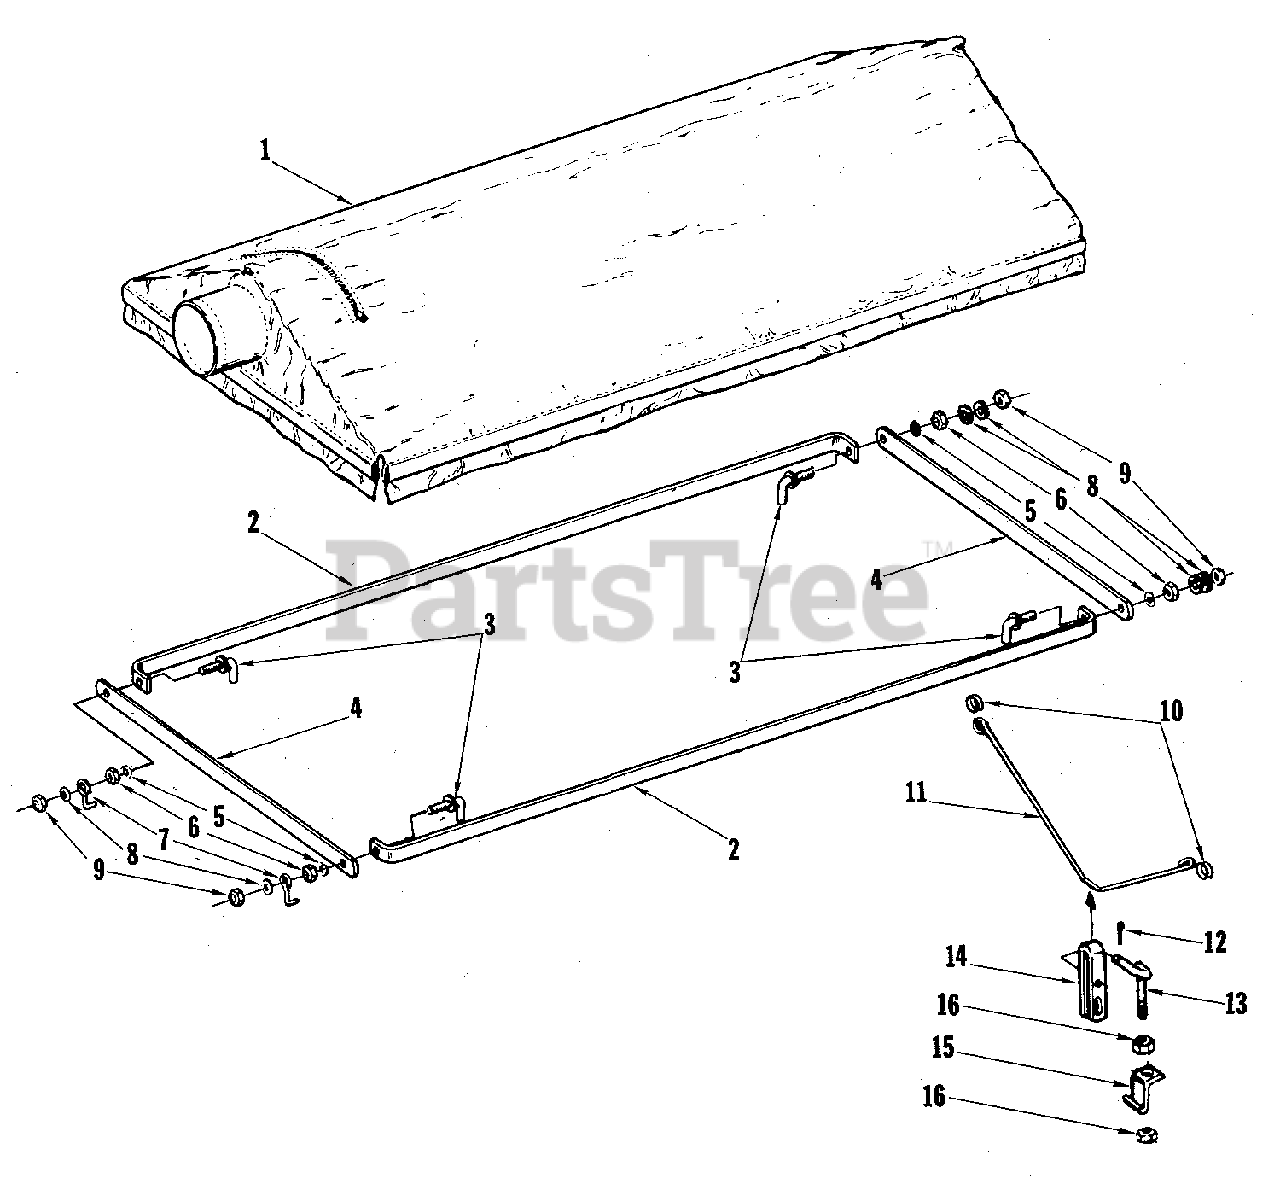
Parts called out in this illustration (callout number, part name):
2	SIDE MEMBER, Frame
3	STUD ASSEMBLY, Special
4	END BRACKET, Frame
5	WASHER, Lock, 5/16"
6	NUT, Hex, 5/16-18
8	WASHER, Flat, 5/16
9	NUT, Hex, Lock, 5/16-18
10	LINK, Repair
12	PIN, Cotter, 1/8 x 1
16	NUT, Hex, Lock, 3/8-16
